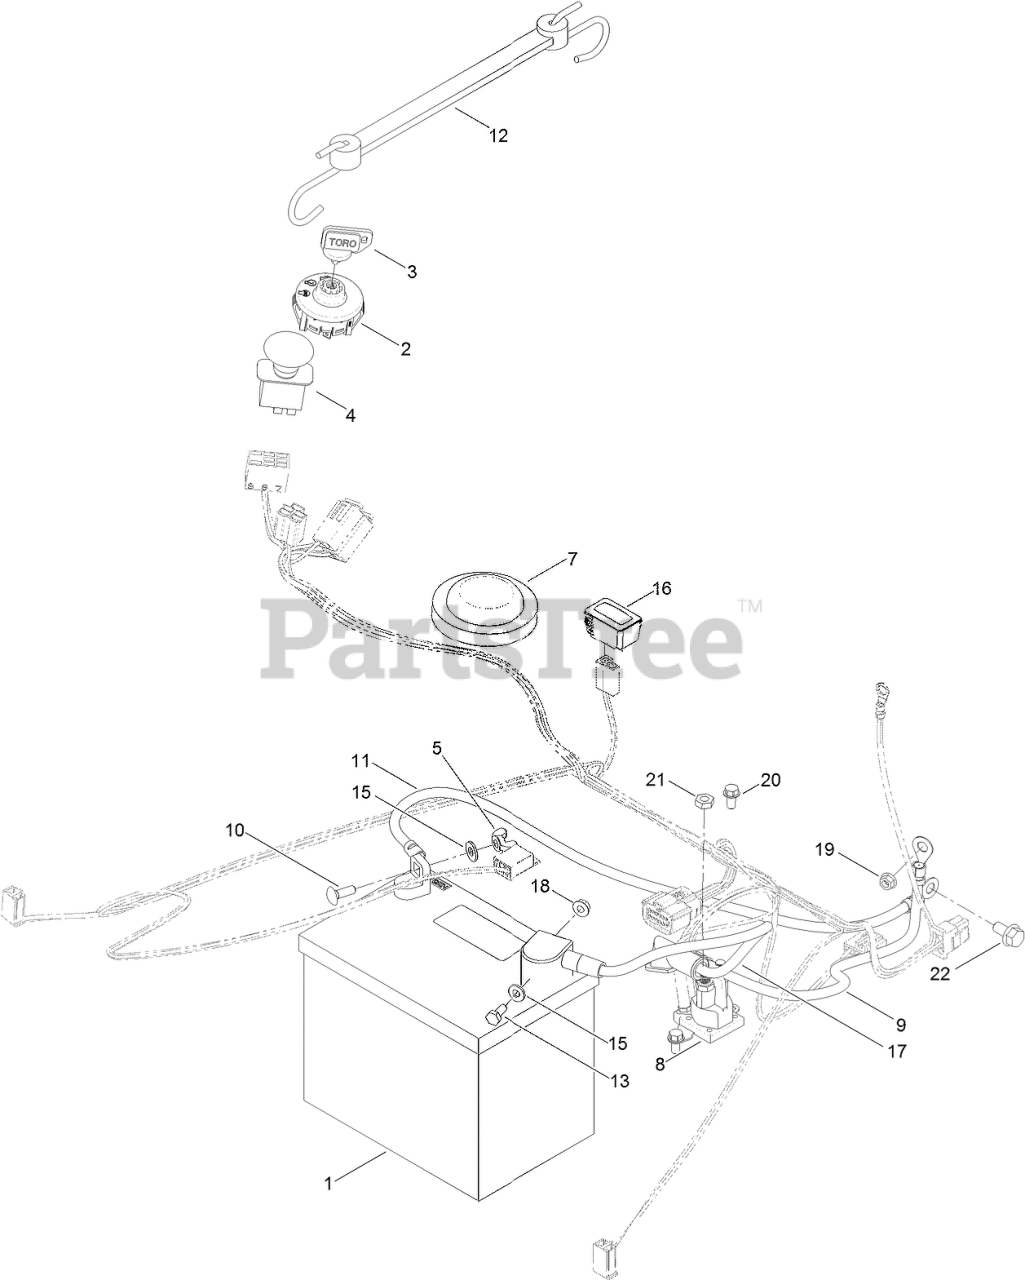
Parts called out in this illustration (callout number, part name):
1	BATTERY
2	SWITCH-IGNITION
3	KEY-IGNITION
4	SWITCH-PTO
5	NUT-WING
7	SWITCH-SEAT
8	SOLENOID
9	CABLE-BATTERY, POSITIVE
10	BOLT-CARR
11	CABLE-BATTERY, BLACK
12	HOLDDOWN-BATTERY
13	SCREW-HH
15	WASHER-FLAT
16	HOURMETER
17	CABLE-BATTERY, RED
18	NUT-HF
19	NUT-HF
20	SCREW-HWH
21	NUT-JAM
22	SCREW-HHF
